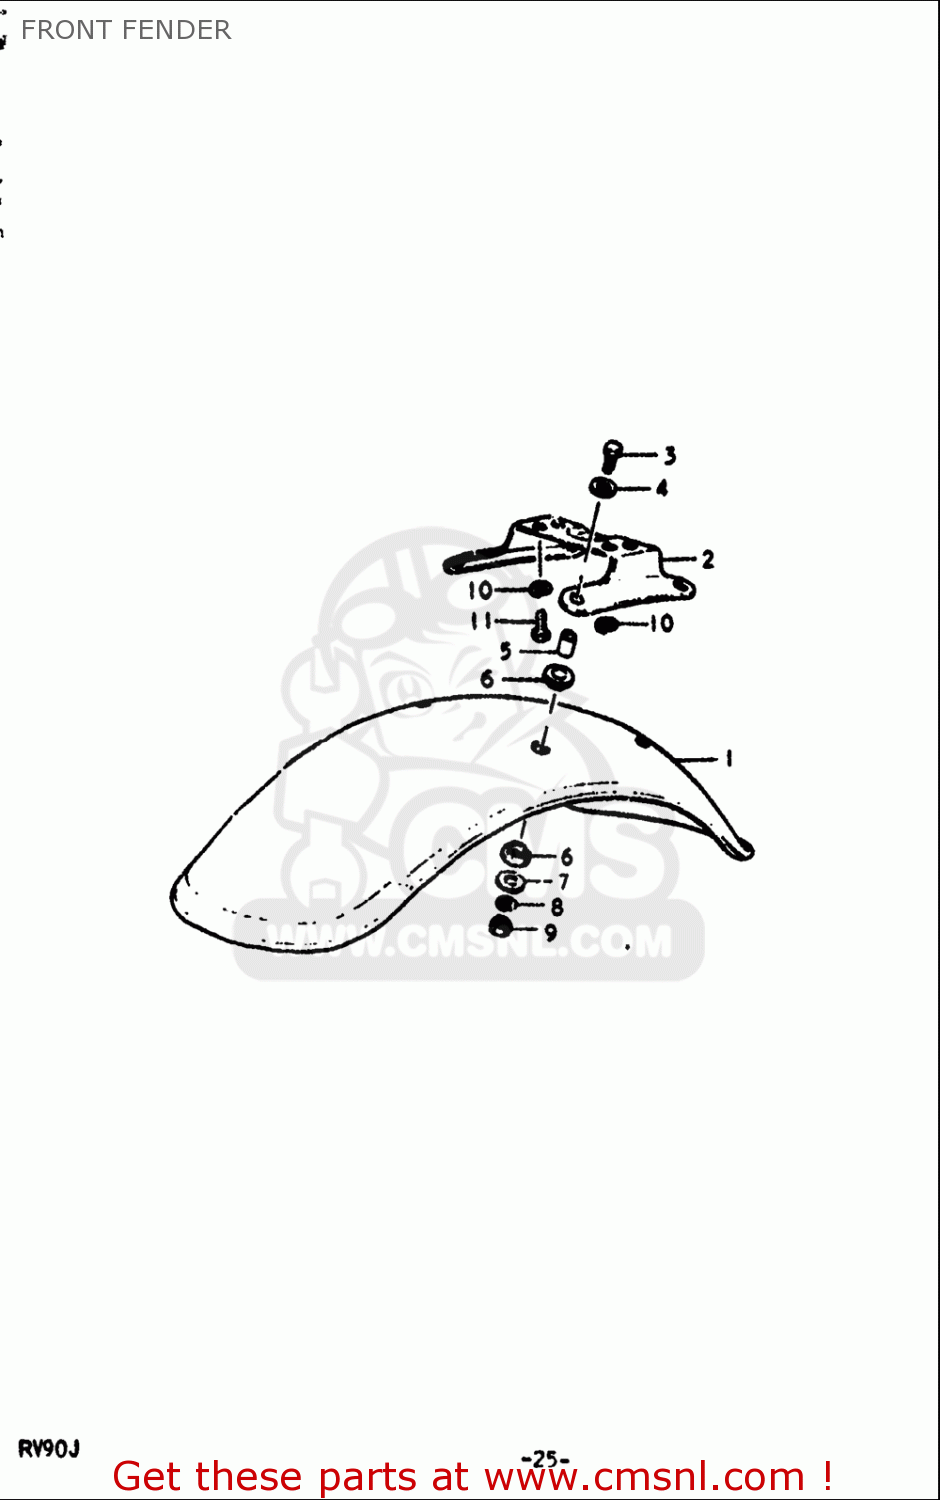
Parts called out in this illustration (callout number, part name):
3	BOLT
4	WASHER
5	SPACER (6.8X10X11.5)
6	CUSHION
7	WASHER(6.5X24X1.2)
8	WASHER,LOCK
9	NUT
10	WASHER,LOCK
11	BOLT
